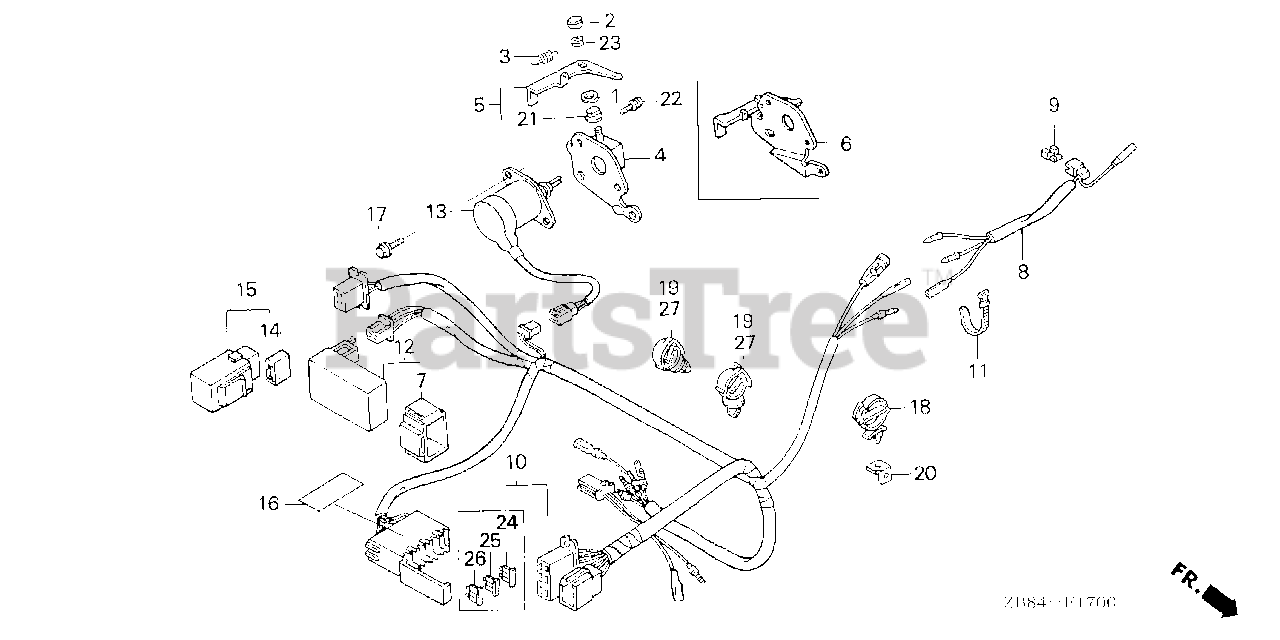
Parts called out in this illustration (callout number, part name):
3	SPRING, CHOKE RETURN
6	LEVER, THROTTLE
7	RUBBER, IGNITION CONTROL MODULE
8	DIODE ASSY., SOLENOID
10	SUB-WIRE HARNESS ASSY.
11	BAND B1, WIRE
12	CONTROL UNIT ASSY., SOLENOID
13	SOLENOID ASSY.
14	SUSPENSION, TURN SIGNAL RELAY (MITSUBA)
15	TIMER UNIT
16	LABEL, FUSE
17	BOLT, FLANGE (6X12) (CT200)
18	STRAP, WIRE HARNESS (25MM) (BLACK)
20	BASE, WIRE CLIP
22	SCREW, PAN (5X8)
25	FUSE, BLADE (5A)
26	FUSE, BLADE (10A)
27	CLIP, WIRE HARNESS (25MM)
